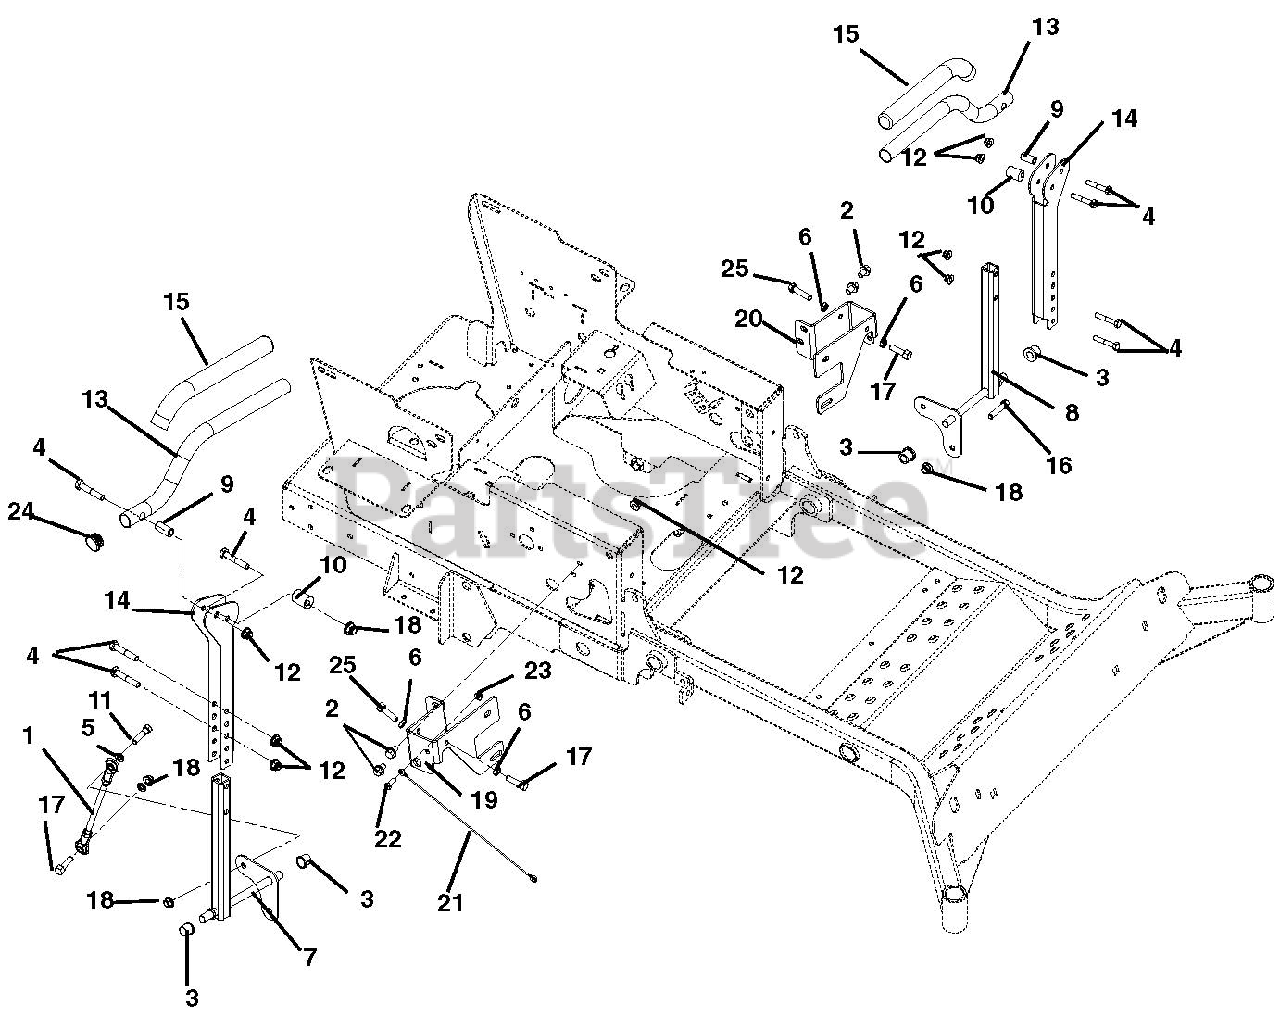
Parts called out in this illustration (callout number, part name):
1	ASM, STEERING LINKAGE
2	@SCR-TAP .38-16X.50 HWH TR YWZ
3	BSHG-FLG .515X.750X.745X1.00NY
4	@BLT-HEX .31-18X1.75 GR5 YWZC
5	@WSHR-LK .38X.094 REG YWZC
6	NUT-HEX-JAM .375-16 YWZC
7	WMT, RH CTRL ARM
8	WMT, LH CTRL ARM
9	BSHG, SPCR .330X.500X1.01 PM
10	BSHG,ECCEN .328X.750X1.01 PM
11	@BLT-HEX .38-16X1.50 GR5 YWZC
12	@NUT-LK-NYL-FLG .31-18 YWZC
13	HANDLEBAR, ZTXL
14	BRKT, STEERING CONTROL (HD)
15	GRIP - HANDLEBAR
16	BLT-HEX .38-16X2.0 GR5 FTD YWZ
17	@BLT-HEX .38-16X1.25 GR5 YWZC
18	@NUT-LK-NYL-FLG .38-16 YWZC
19	RH STEERING STOP BRKT - BLK
20	BRKT, LH STEERING STOP
21	CABLE, 12.0 LANYARD, NYLON
22	@BLT-HEX .25-20X.75 GR5 YWZC
23	@NUT-LK-NYL-FLG .25-20 YWZC
24	CAPLUG, HANDLEBAR
25	@BLT-HEX .38-16X.75 GR5 YWZC
